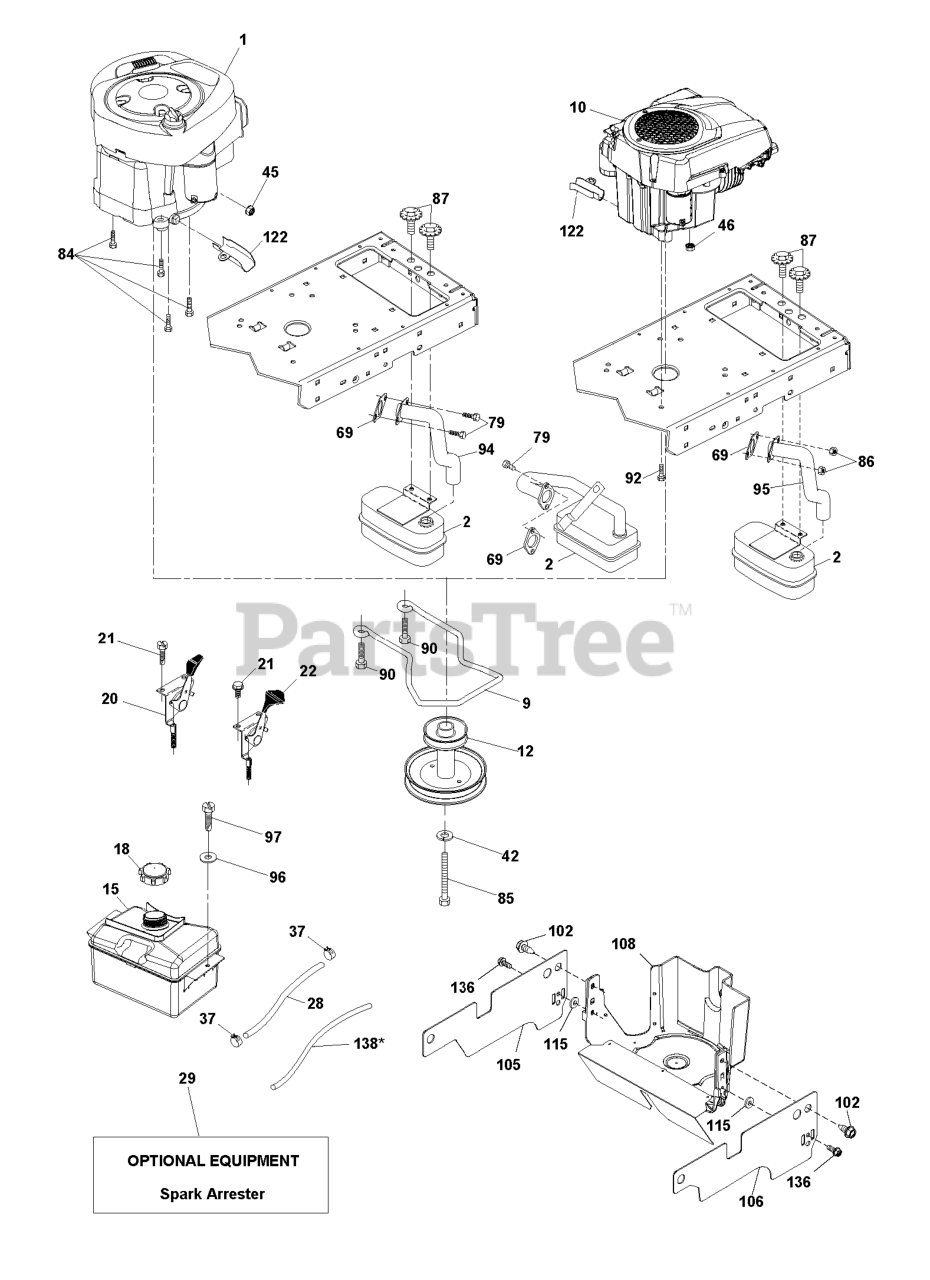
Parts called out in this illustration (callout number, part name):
2	MUFFLER.LT.BRIGGS.14HP.IC/OHV
2	MUFFLER.SINGLE.CYL.KOHL/B&S
2	MUFFLER.ASM.SINGLE
9	Keepers
9	KEEPER.BELT.ENG.4.25"2.BLT.431
9	KEEPER.BELT.ENG.3.25"2BOLT.PNT
10	ENGINE.LONCIN.SPARE/452
12	ENGINE.PULLEY
12	PULLEY.ENGINE
15	Tanks
15	FUEL.TANK.ASM.NON-EPA
18	CAP ASM.FUEL.2.25"FR.
20	THROTTLE CABLE
20	THROTTLE.COBRA.21".RSTART.BLK
21	SCREW.#10 X 0.750.BOS
22	CONTROL.TH/CK.C.
28	HOSE.1/4".LOW.PERM.FUEL.LN.22"
28	LINE.FUEL.20
28	HOSE 1/4" LOW PERMEATION FUEL
29	KIT.SPARK ARRESTOR 794945 B&S
37	HOSE CLAMP
42	WASHER 7/16 LOCK
45	Hardware
45	NUT HEX_LRG FLG_1_4-20_LOCK
46	NUT HEXAGON WITH FLANGE, SERRA
69	REPL BY 532 27 22-93
69	GASKET GASKET.EXHAUST.LONCIN 3
69	GASKET.EXHAUST.KOHLER
79	Screws
84	SCREW.3/8-16
85	BOLT.HEX.7/16-20X4.GR5.1.5BLUE
86	NUT.HEX.FLANGE.TOPLOCK
87	BOLT.5/16-18UNCX3/4 W/SEMS.BLK
90	SCREW 3/8-16X1
92	SCREW 3/8-16X1
94	EXHAUST.TUBE.B&S.28/31
95	TUBE TUBE.EXHAUST.LONCIN 452.T
96	WASHER
97	SCREW HEXWSHR 1/4-20X3/4
102	SCREW
105	SHIELD.SIDE.LH.3842"TEX FRN.BK
106	SHIELD.SIDE.LH.3842"TEX FRN.BK
108	COVER ENGINE PULLEY COVER WITH
115	RETAINER
122	EXTENSION DRAIN OIL
136	SCREW.#10 X 0.500
